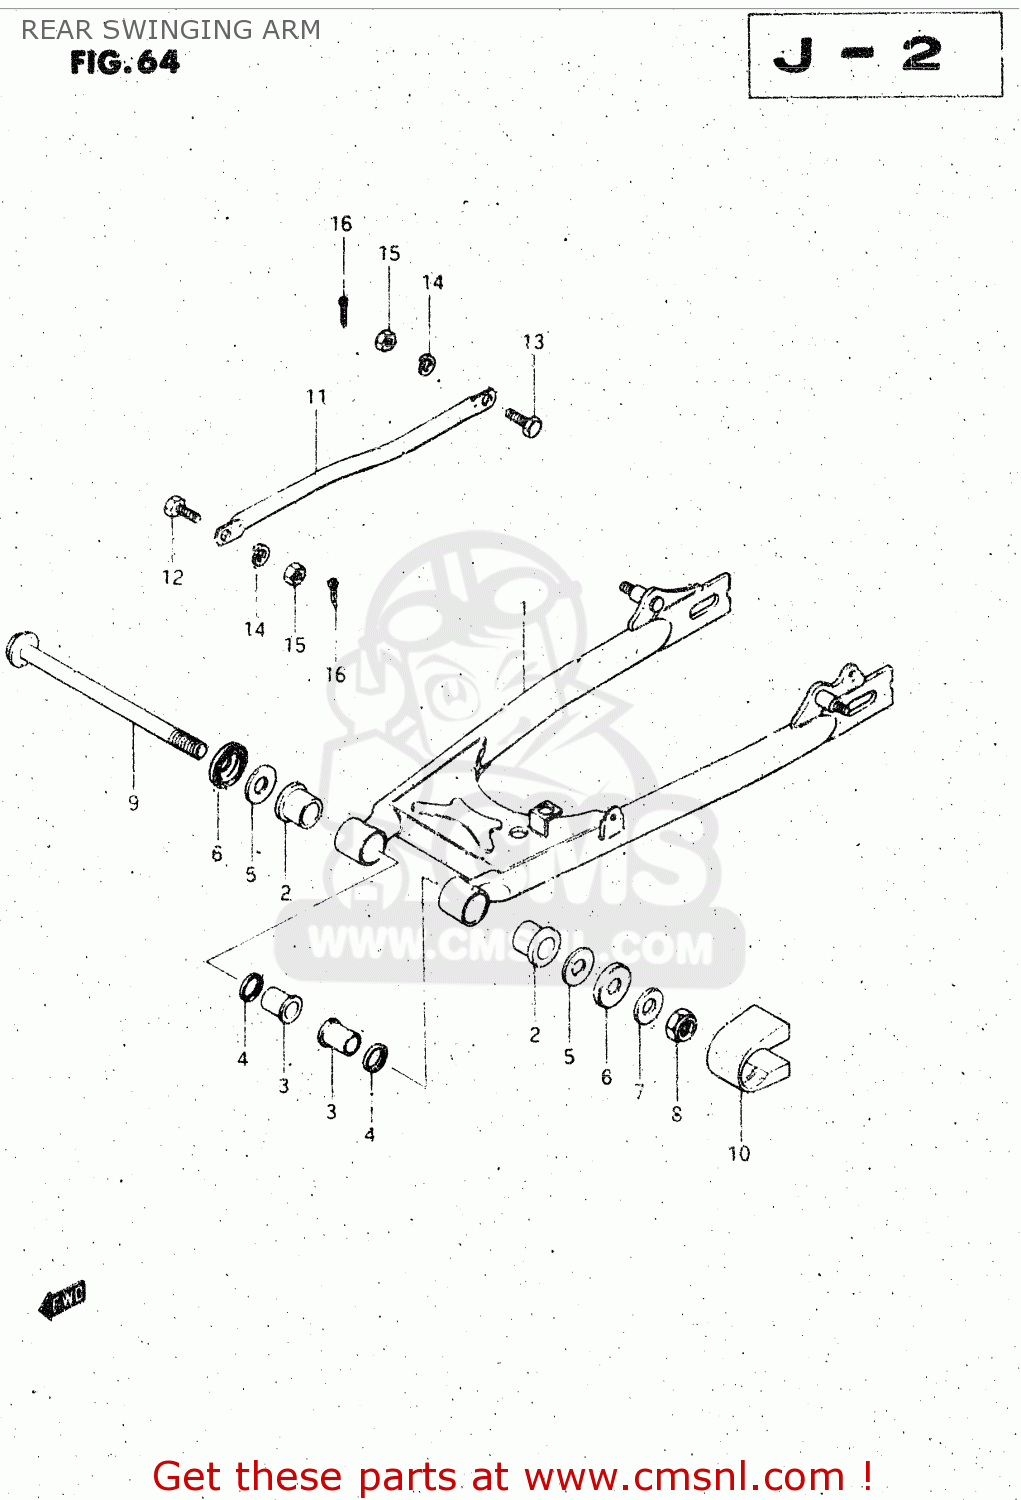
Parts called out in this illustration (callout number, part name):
1	SWINGINGARM ASSY,RR
2	BUSH,RR SWINGING ARM PIVOT
3	SPACER,RR SWGARM PIVOT
4	SEAL,OIL(20X27X5)
5	WASHER
6	CVR,RR SWGARM DUST SEAL(OD:40)
7	WASHER
8	NUT 14MM
9	SHAFT,REAR SWING ARM
10	BUFFER,CHAIN TOUCH DEFENSE
11	TORQUELINK,RR
12	BOLT(8X22.5)
13	BOLT(8X26.5)
14	WASHER,LOCK
15	NUT
16	PIN 20X20
